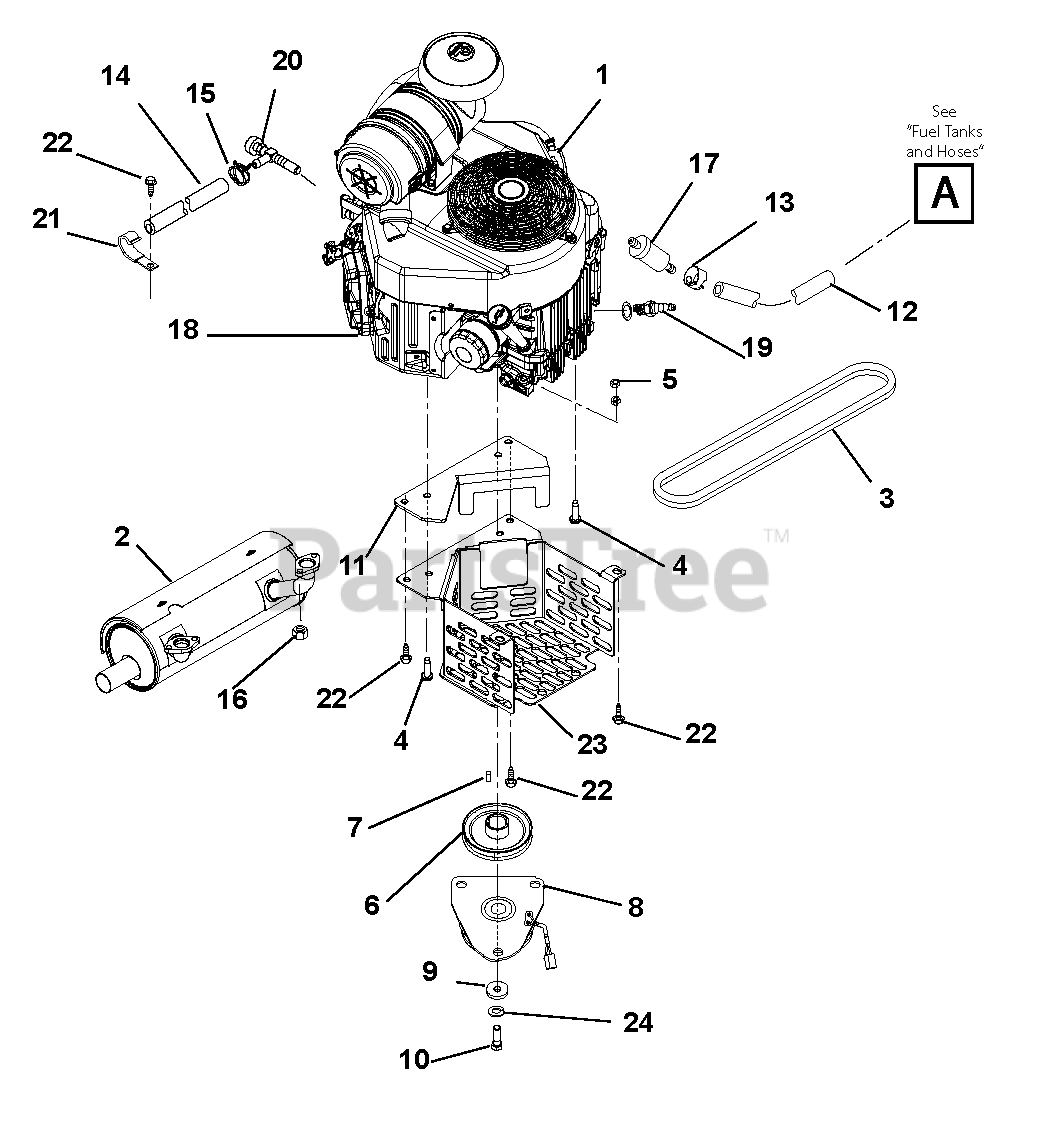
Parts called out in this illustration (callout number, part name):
1	Engine, Kawasaki FX 481
2	Muffler, Kawasaki
3	V-Belt, 53.7 Inches
4	Bolt, Hex .38-16 x 1.25 FTH G5 EP80 YZ
5	Nut, Locking Nylon Flange .31-18
6	Pulley, 4.50 OD x 1.127 Engine
7	Key, Square .25 x .625 x .25 SAE 8630 or SAE 1035
8	Clutch, Ogura
9	Washer, Flat Steel .463 x 1.375 x .250
10	Bolt, Hex .44-20 x 1.50 Grade 5 EP80
11	Anchor, Clutch, CE
12	Hose, Gas Line .25" I.D.
13	Hose, Clamp
14	Hose, .50 x 6.00
15	Clamp, .88 Diameter Hose
16	Nut, Top Lock M8-1.25
17	Fuel Filter, Kawasaki
18	Oil Filter, Kawasaki
19	Spark Plug, Kawasaki
20	Drain, .50 Oil
22	Screw, Tapping .38-16 x .75 Hex Washer Head
23	Weldment, Anchor and Belt Guard
24	Washer, Locking .44
